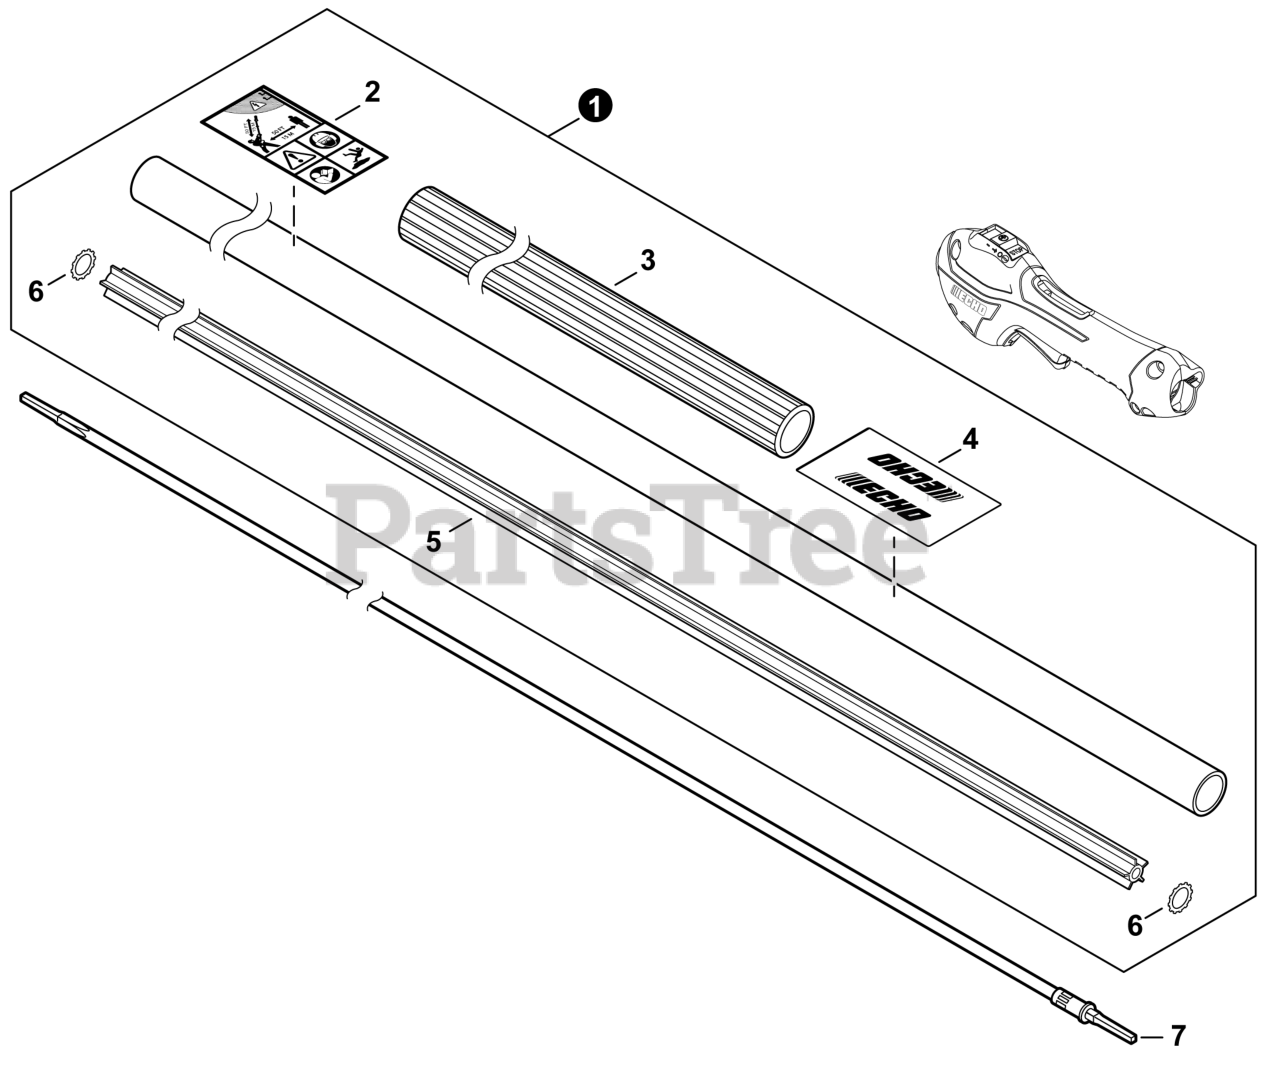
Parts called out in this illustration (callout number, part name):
1	MAIN PIPE ASSY
2	LABEL - CAUTION
3	GRIP, FRONT
4	LABEL - HANDLE LOCATION
5	LINER - FLEXIBLE
7	DRIVESHAFT - FLEXIBLE
